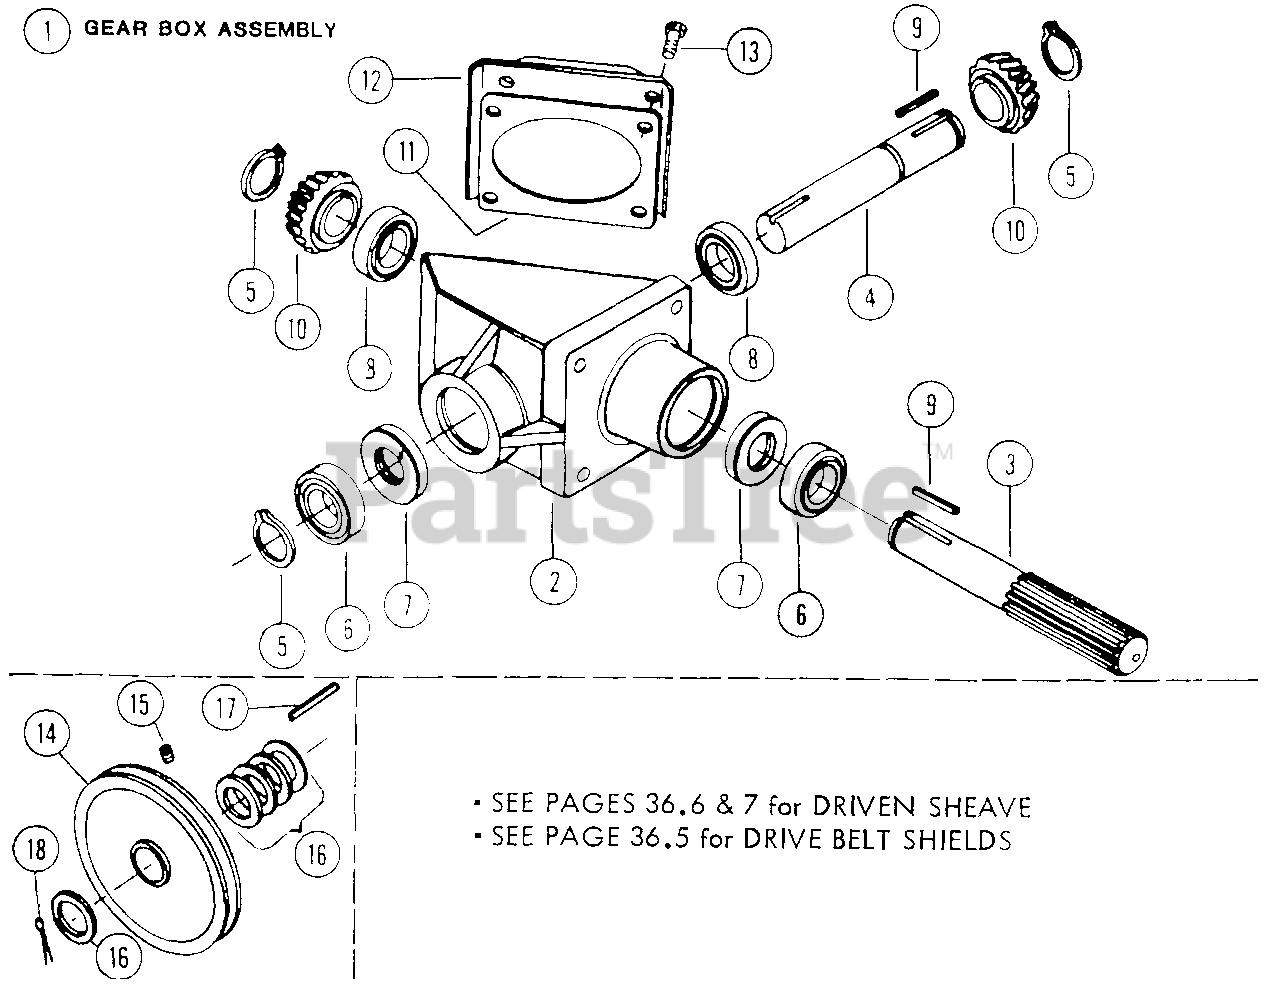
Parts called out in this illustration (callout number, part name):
1	GEAR BOX ASSEMBLY, 1:1 RATIO
2	HOUSING, GEAR BOX
5	RING, RETAINING
6	BEARING, BALL - OUTER
7	SEAL, OIL
8	BEARING, BALL - INNER
11	GASKET, LID
13	BOLT, LID RETAINING
14	SHEAVE, DRIVE
15	SETSCREW, 5/16-18 x 1/2 HEX SOCKET
16	WASHER, SPECIAL .765" ID, 1.25" OD, 14 GA.
17	KEY, 3/16x3/16x1"
18	PIN, 1/8 x 1-1/2 COTTER
